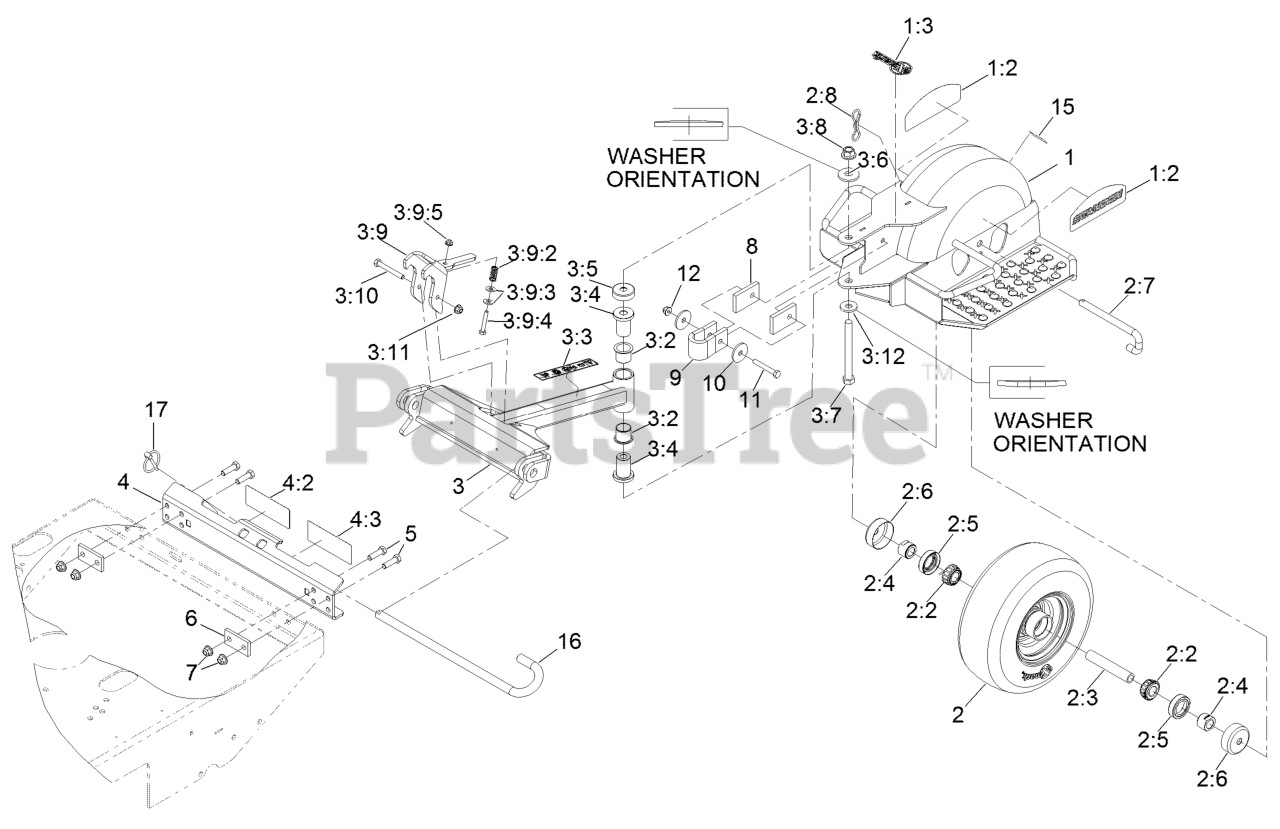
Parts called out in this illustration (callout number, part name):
1	ASM-SULKY FRAME W/ DECALS
1:2	DECAL, STANDON
1:3	DECAL, EXMARK
2	ASM, WHEEL AND BEARINGS
2:2	BEARING-CONE, TAPERED ROLLER
2:4	SPACER-NUT
2:5	SEAL-CASTER
2:6	GUARD-SEAL
2:7	PIN, CASTER
2:8	PIN-COTTER, LOCKING
3	ASM, DRAW BAR
3:2	BUSHING-PIVOT
3:3	DECAL-SULKY HAZARD
3:4	SPACER, PIVOT
3:5	COVER, DUST
3:6	WASHER-BELLEVILLE
3:7	SCREW-HH
3:8	Nut-Lock 1/2-13
3:9	TRANSPORT LATCH ASM
3:9:2	SPRING, COMPRESSION
3:9:3	WASHER-FLAT
3:9:4	SCREW-HH
3:10	SCREW-HH
3:11	NUT-HF, NI
3:12	WASHER-SPRING
4	ASM, MOUNT PLATE
4:2	DECAL-BELT DRIVE WARNING
4:3	DECAL-WARNING, SULKY
5	SCREW-HH
6	PLATE,BACK-UP (PLATED)
7	NUT-HF, NI
8	PAD,STOP
11	SCREW-HH
12	NUT-HF, NI
15	Decal-Patent Ttco.Com
16	PIN, PIVOT
17	PIN-LYNCH
